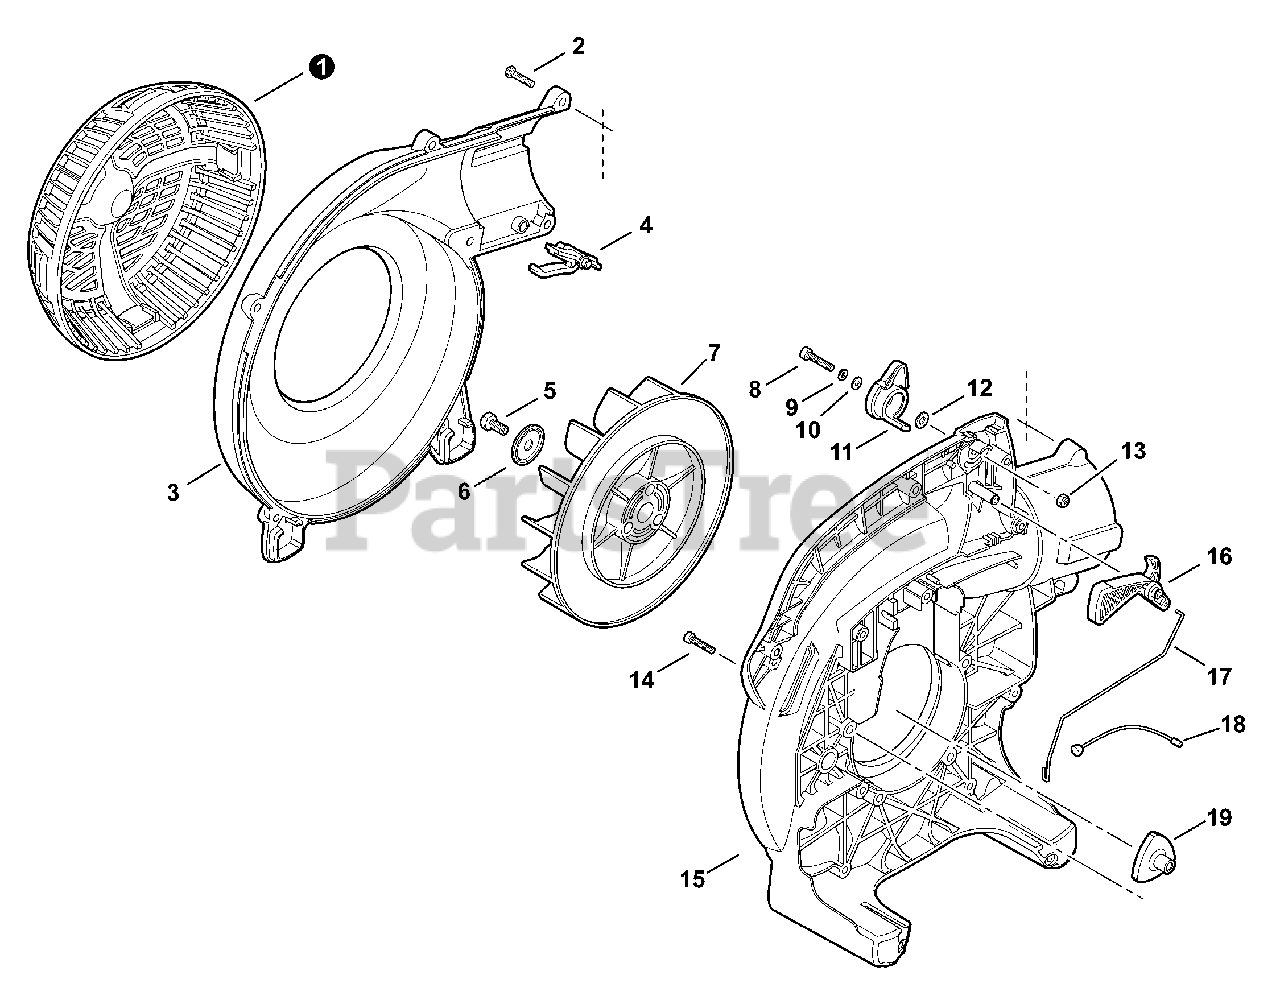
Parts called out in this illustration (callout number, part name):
1	GUARD, FAN
2	BOLT, TORX 5×20
3	COVER, FAN
4	LOCK, TUBE
5	BOLT 8×14
6	WASHER 8.2×31×0.8
7	FAN, BLOWER
8	BOLT, TORX 5×25
9	WASHER, SPRING 5
10	WASHER 5.3×10×1
11	CONTROL, THROTTLE
12	WASHER 5.5×12×0.8
13	NUT, LOCK M5
14	BOLT, TORX 4×20
15	CASE, FAN
16	TRIGGER, THROTTLE
17	ROD, THROTTLE
18	CABLE, THROTTLE
19	HUB, FAN
